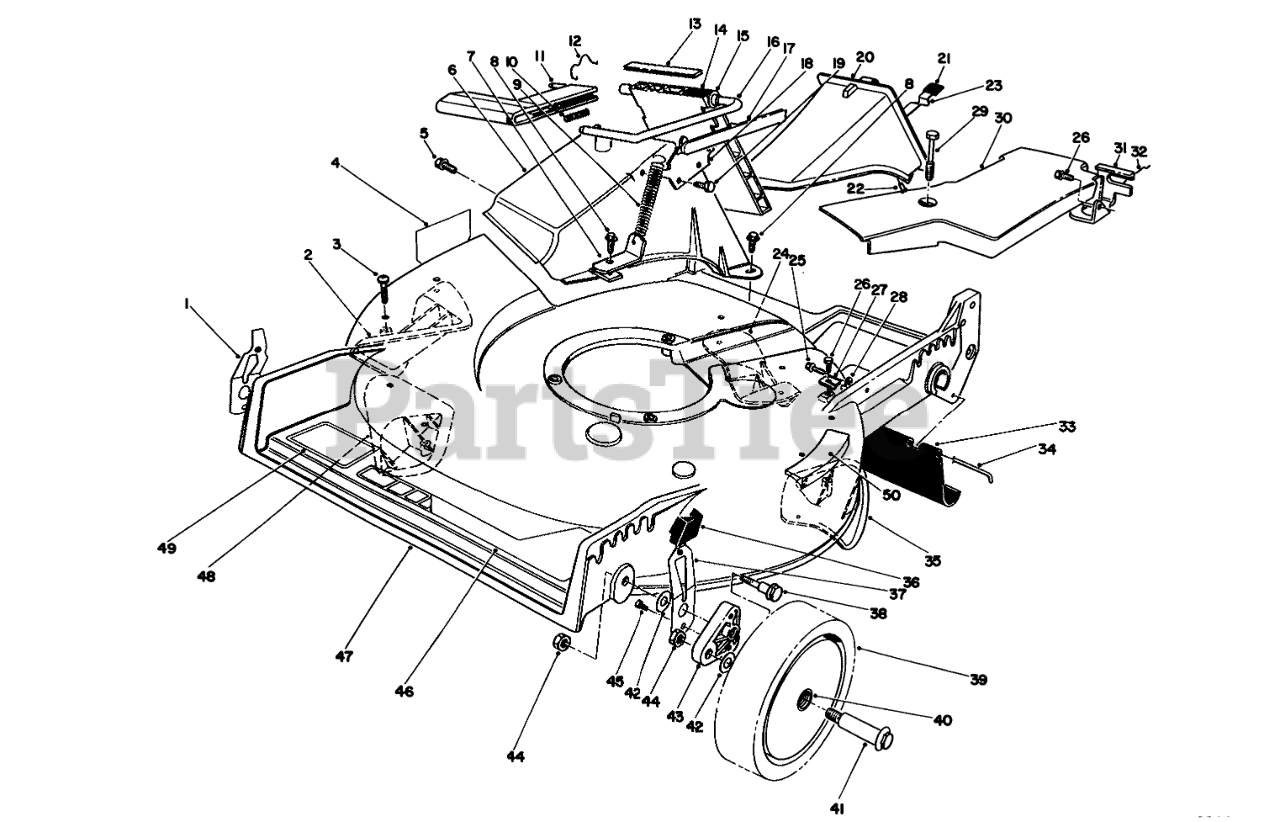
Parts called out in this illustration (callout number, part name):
1	RH SPRING ARM ASSEMBLY
2	KICKER
3	#8 X .625" PHILPS PAN H
4	DECAL-DANGER
5	SCREW AND WASHER ASM
6	Tunnel-Discharge
7	Bracket-Spring
8	SCREW-HWH
9	SPRING-DOOR
10	Spring
11	Handle-Door
12	DOOR RET SPRING
13	Cover-Door
14	Door-Discharge
15	BUSHING-NYLON
16	Rod-Door
17	Cover-Handle
18	DOOR LATCH PLATE
19	SCREW-PLASTITE
20	Plug Assembly (Incl. Ref. #21-23)
21	GRIP-LATCH
22	RIVET-HEAD, FLAT
23	LATCH-PLUG, DISCHARGE
24	KICKER
25	SCREW
26	SCREW-HWHTF
27	CLAMP-CABLE
28	CLAMP-CABLE
29	SCREW-HHFTF
30	Cover-Belt
31	Bracket-Traction Adj.
32	RETAINER-CABLE
33	SHIELD-TRAILING
34	ROD-SHIELD
35	KICKER
36	KNOB-ARM
37	LH SPRING ARM ASSEMBLY
38	SCREW-SHOULDER
39	Wheel & Tire Assembly (Incl. Ref. #40)
40	BUSHING
41	WHEEL BOLT
42	WASHER
43	ARM-PIVOT, FRONT
44	Nut
45	SCREW-HWH
46	DECAL - DECK
47	Housing Assembly (Incl. Ref. #4 & 50)
48	KICKER
49	DECAL
50	STEP PAD DECAL
